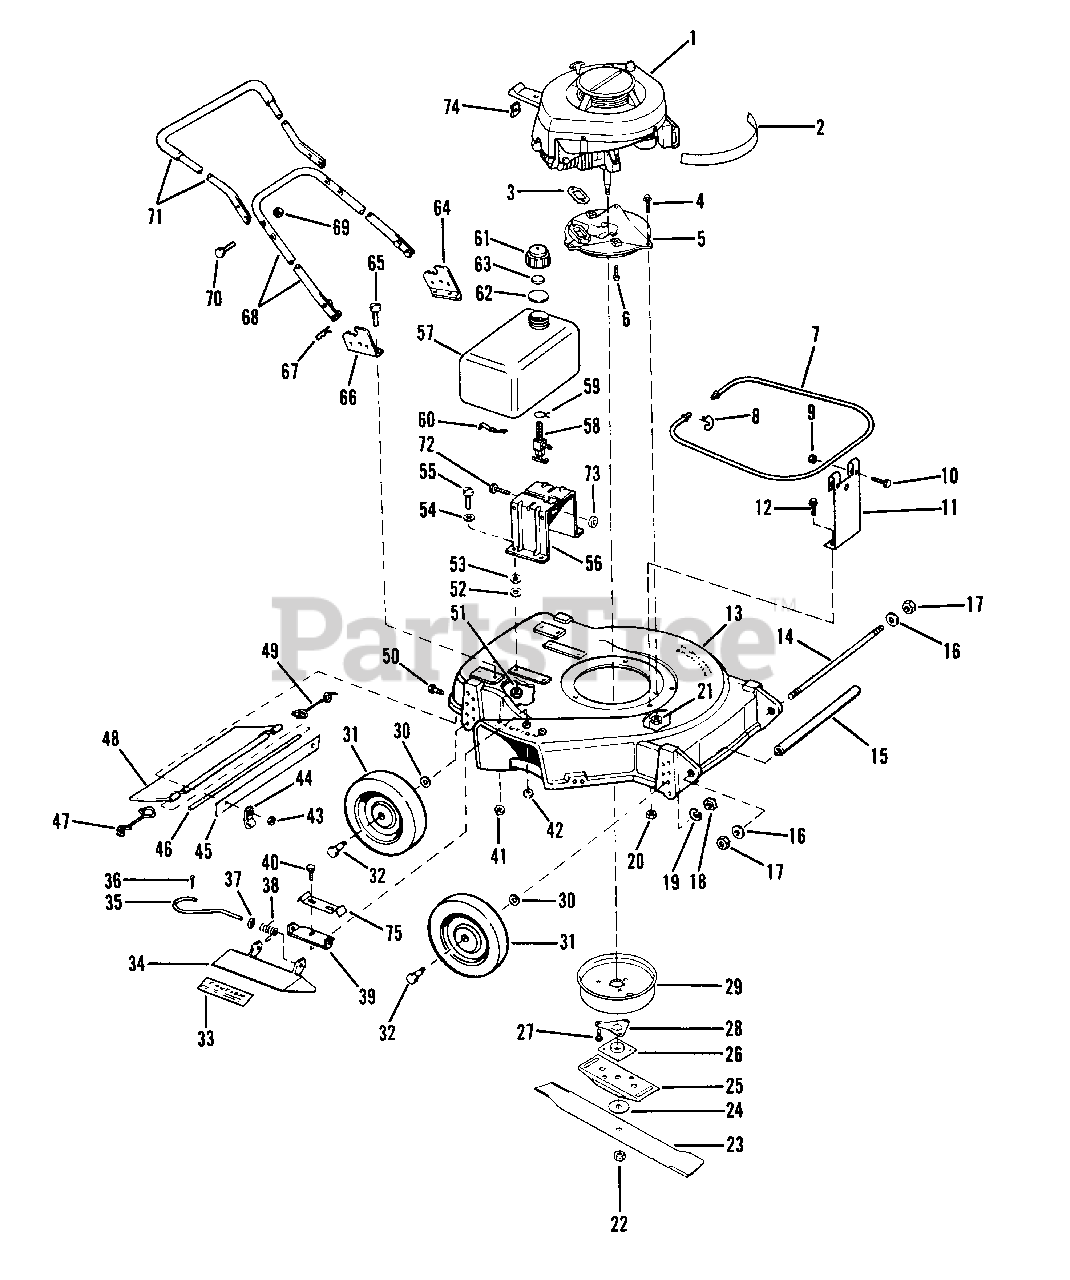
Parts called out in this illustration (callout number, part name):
1	Engine Assembly, Model F 200, Commercial
2	Decal-Lawn-Boy
3	Gasket-Exhaust
4	Screw-Muffler Plate to Housing
5	Plate-Muffler
6	Screw-Muffler Plate to Block
7	Guard-Engine
8	Clip-Engine Guard
9	Nut
10	Screw-Guard to Support
11	Support-Guard
12	Screw-Support to Housing
13	Housing & Bar Assembly
14	Rod-Bumper
15	Bumper
16	Washer-Mounting
17	Nut-Bumper Mounting
18	Nut-Wheel Mounting
19	Lockwasher-Wheel Mounting
20	Nut-Support Guard to Housing
21	Nut-Muffler Plate to Housing
22	Nut-Blade
23	Blade-21"
24	Washer-Blade
25	Stiffner-Blade
26	Collar & Plate Assembly
27	Screw
28	Support-Crankshaft
29	Muffler Cover Assembly
30	Washer-Wheel Bolt
31	Wheel & Tire Assembly-8"
32	Wheel Bolt
33	Decal
34	Deflector
35	Pin
36	Cotter Pin
37	Push Nut
38	Spring
39	Plate
40	Screw
41	Nut-Handle Bracket Mounting
42	Nut-Deflector Mounting
43	Nut-Rod Clamp Screw
44	Clamp
45	Extension
46	Bar
47	Spring-R.H.
48	Shield-Trailing
49	Spring-L.H.
50	Screw
51	Nut
52	Washer
53	Grommet
54	Washer
55	Screw
56	Bracket-Fuel Tank Mounting
57	Fuel Tank
58	Shut-Off Valve & Screen
59	Clamp
60	Spring-Fuel Tank Mounting
61	Fuel Cap Assembly
62	Gasket
63	Baffle
64	Handle Bracket-L.H.
65	Screw
66	Handle Bracket-R.H.
67	Hair Pin
68	Handle Bottom & Pin Assembly
69	Nut-Handle
70	Screw-Handle
71	Top Handle & Grip Assembly
72	Screw, Tank Bracket to C.D. Bracket
73	Spacer, Tank Bracket to C.D. Bracket
74	Speednut-C.D. Bracket
75	Bracket-Deflector Mounting
